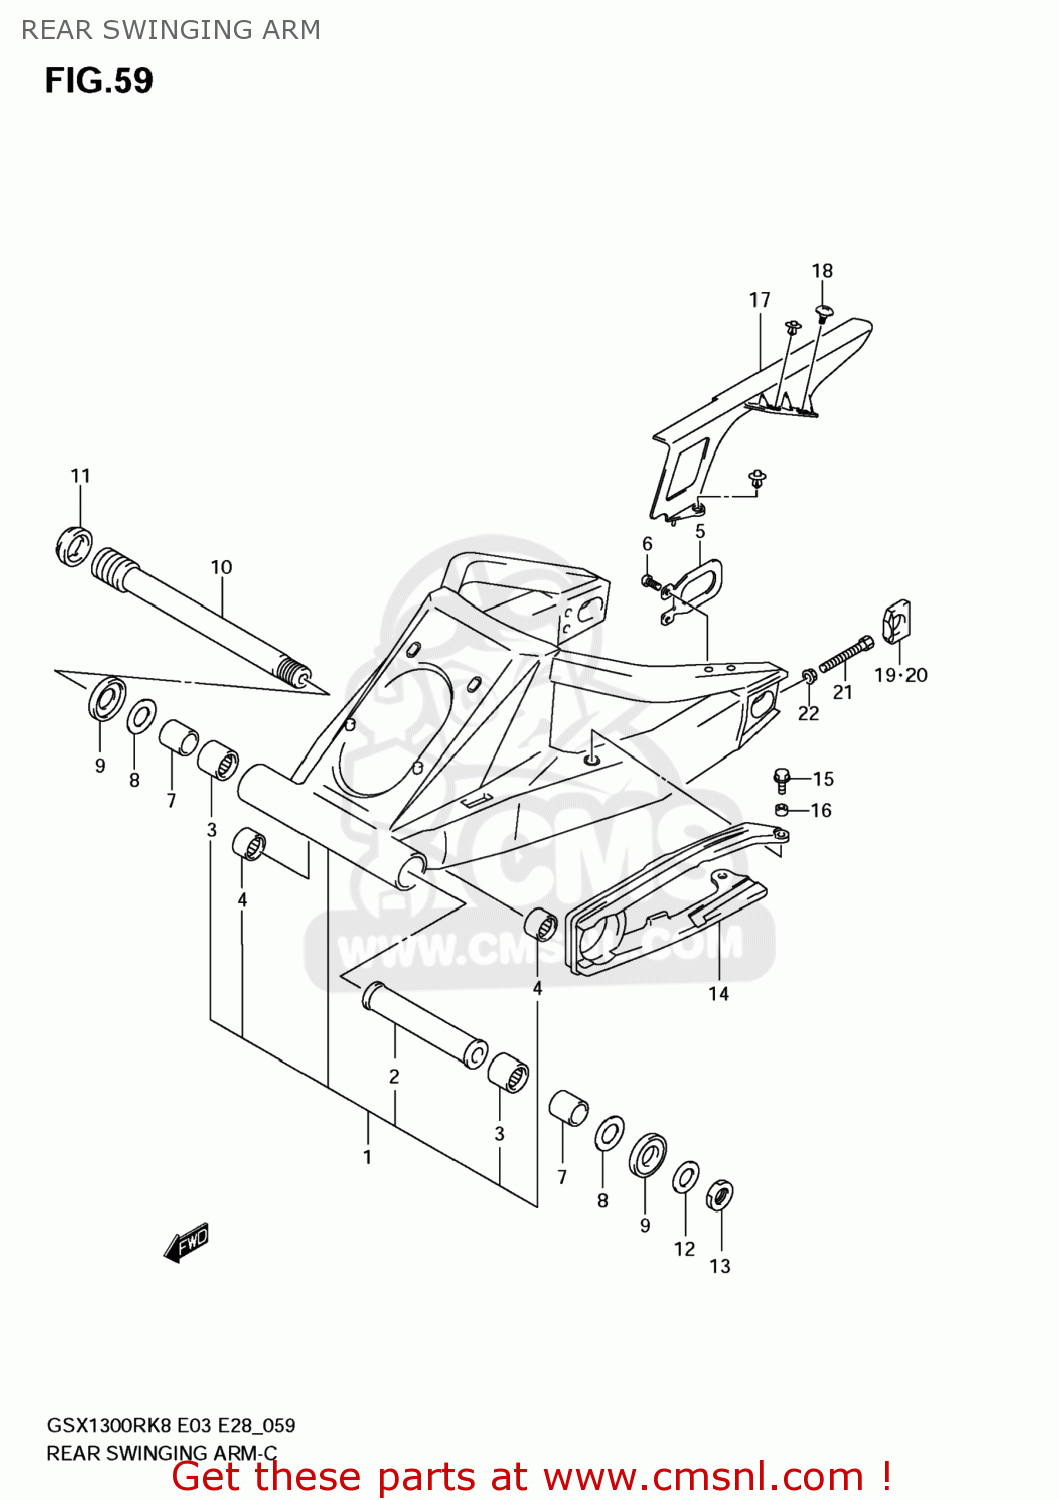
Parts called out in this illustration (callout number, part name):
1	SWINGINGARM ASSY
2	SPACER,RR SWGARM PIVOT CTR
3	BEARING(30X40X25)
4	BEARING(17X24X25)
5	PLATE,RR SWING ARM BRKT
6	SCREW(6X16)
7	SPACER,REAR SWING ARM PIVOT
8	WASHER
9	DUST SEAL,RR SWGARM PIVOT
10	SHAFT,RR SWINGINGARM PIVOT
11	NUT,RR SWGARM PIVOT BOLT
12	WASHER(25.2X42X3.2)
13	NUT
14	BUFFER,CHAIN TOUCH DEFENSE
15	BOLT(6X20)
16	SPACER(6.5X9X5)
17	CASE,CHAIN
18	SCREW(6X16)
19	ADJUSTER,CHAIN
20	ADJUSTER,CHAIN
21	BOLT(8X50)
22	NUT
